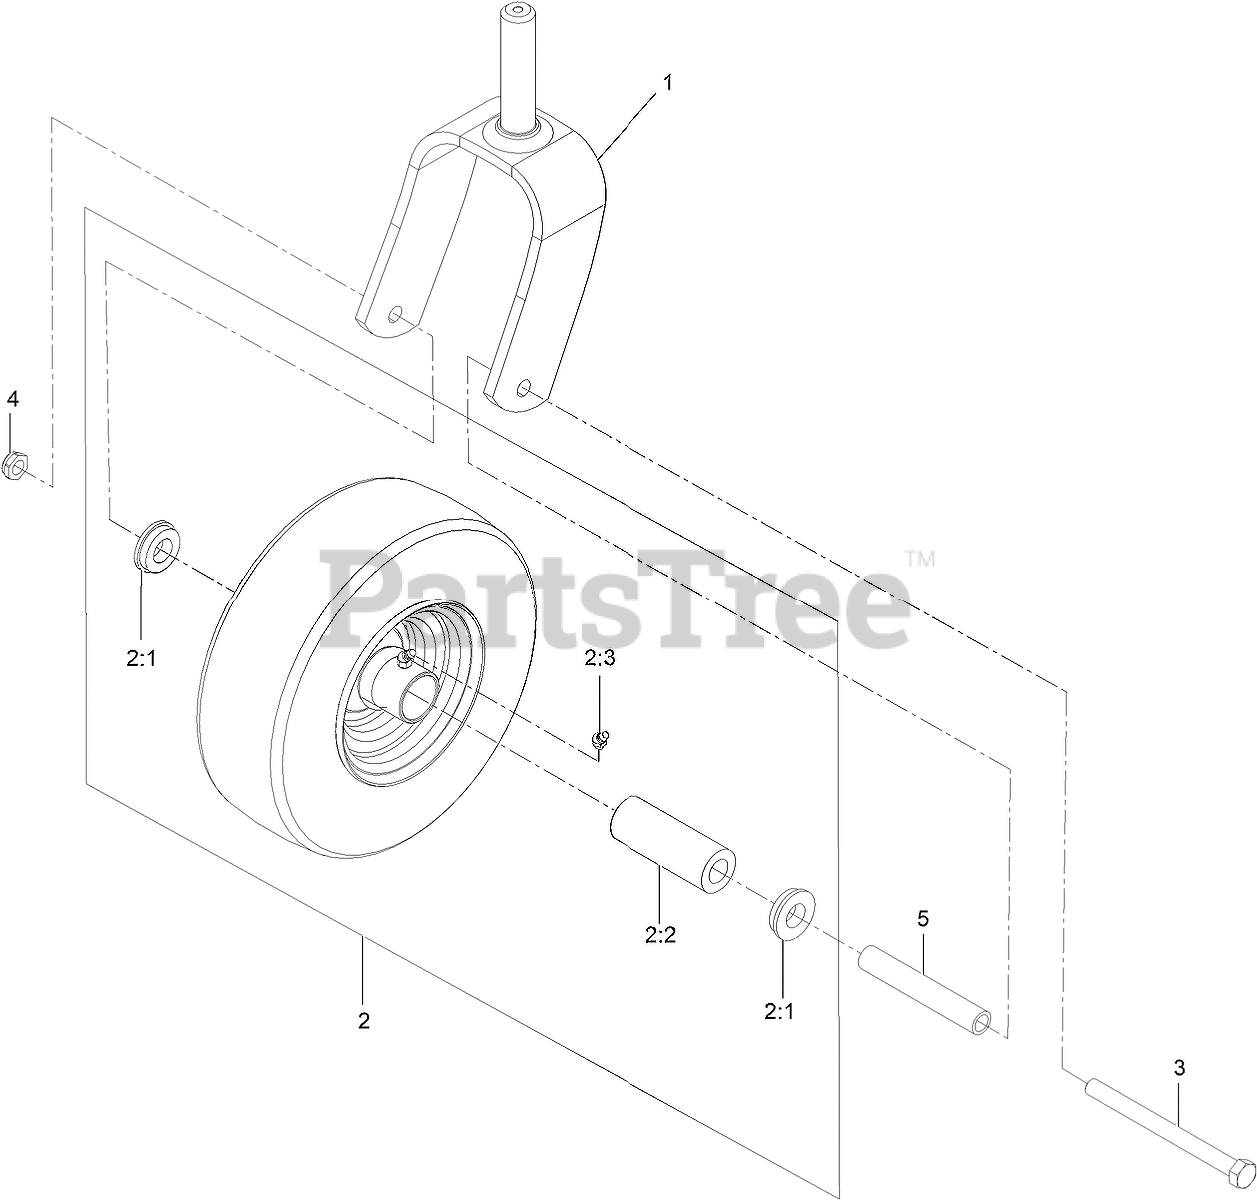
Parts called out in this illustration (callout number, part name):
1	FORK-CASTER
2	WHEEL AND TIRE ASM
2:1	BUSHING
2:2	BEARING
2:3	FITTING-GREASE
3	SCREW-HH
4	NUT-HEX
